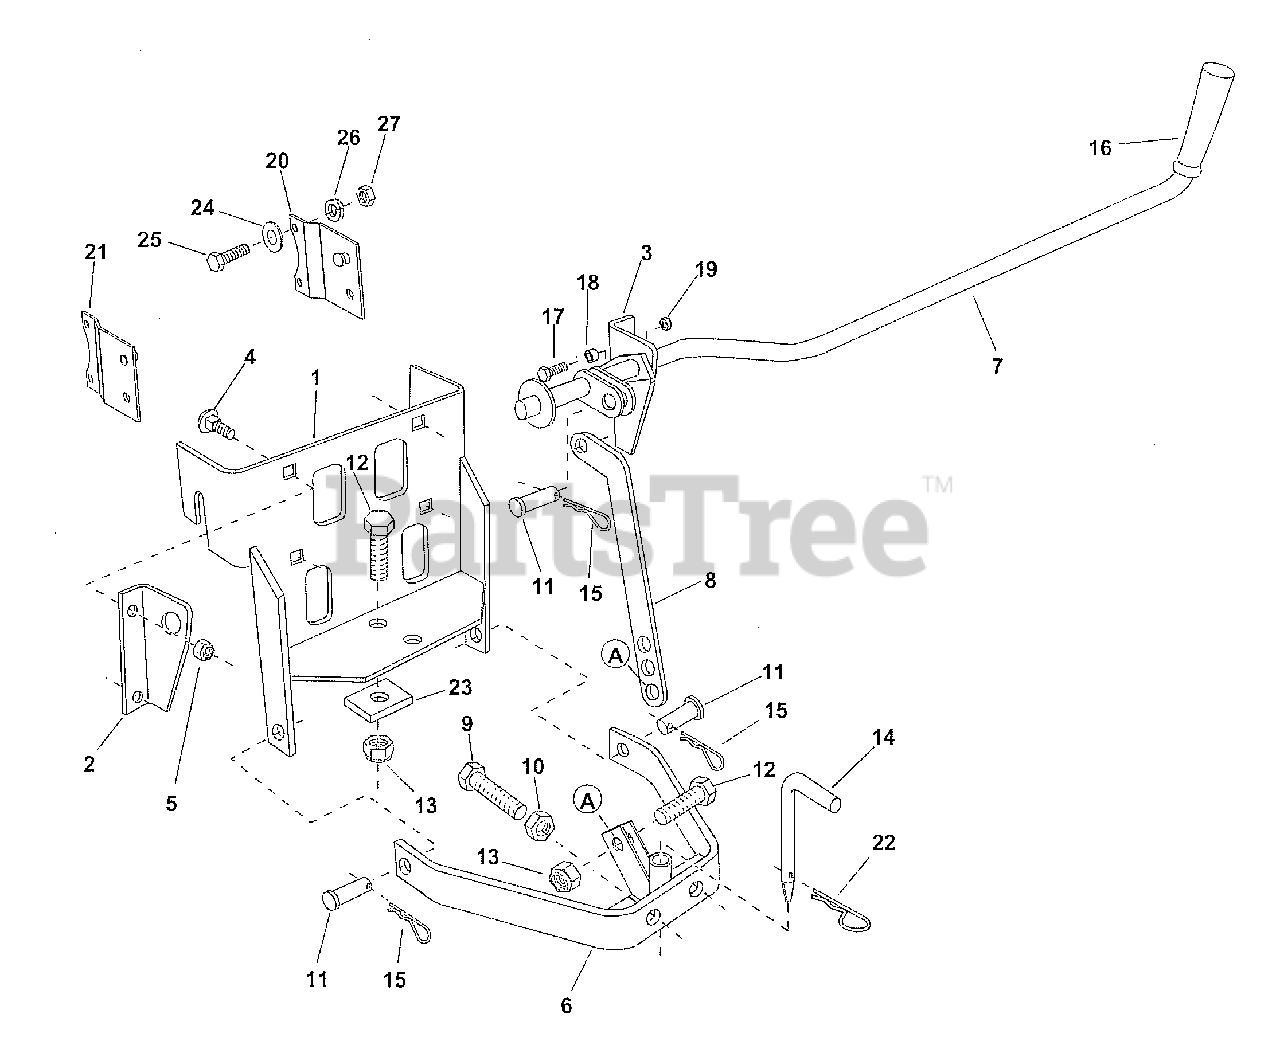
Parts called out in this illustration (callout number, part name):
1	Sleeve Hitch Frame
2	Pivot Bracket, Left
3	Pivot Bracket, Right
4	Bolt, Carriage 3/8-16 x 1"
5	Hex Lock Nut, 3/8-16
6	Sleeve Hitch Lift Assembly
7	Lift Lever Assembly
8	Lifting Link Plate
9	Bolt, Hex 5/8-11 x 2"
10	Hex Jam Nut, 5/8-11
11	Clevis Pin, 5/8" x 1-3/4"
12	Bolt, Hex 5/8-11 x 1-3/4"
13	Nylock Nut, 5/8-11
14	Pin, Sleeve Hitch
15	Pin, Hair Cotter 3/32"
16	Grip, Plastic
17	Bolt, 5/16-18 x 1"
19	Nylock Nut, 5/16"
20	Mounting Bracket, Right
21	Mounting Bracket, Left
22	Pin, Hair Cotter, 5/32"
23	Spacer Plate
24	Flat Washer
25	Bolt, Hex 3/8-16 x 1-1/4"
26	Lock Washer, 3/8"
27	Hex Nut, 3/8-16
